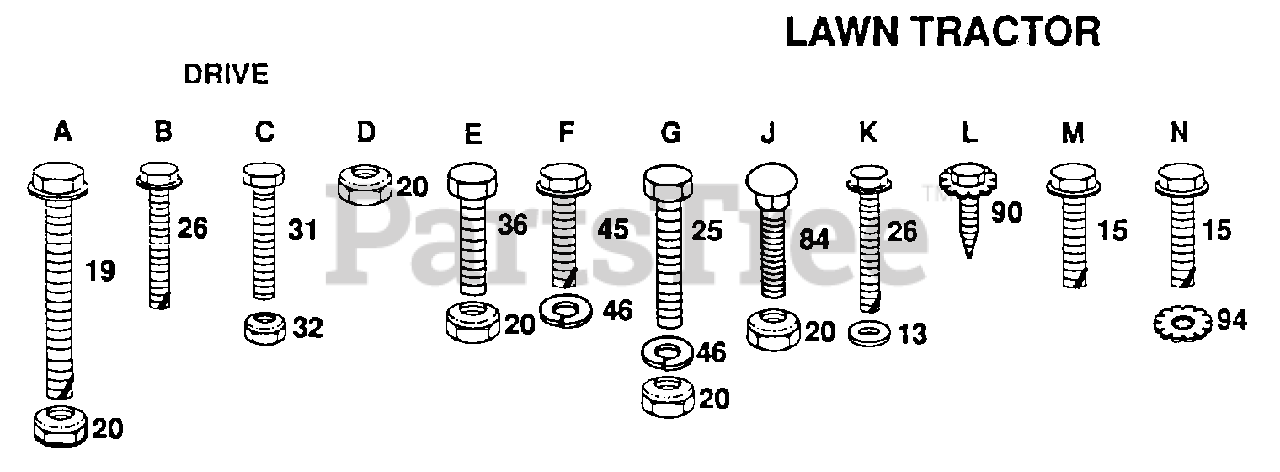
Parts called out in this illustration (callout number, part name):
13	WASHER
15	SCREW
19	BOLT
25	BOLT
26	SCREW
31	BOLT
45	SCREW
46	WASHER
84	BOLT
94	LOCKWASHER
